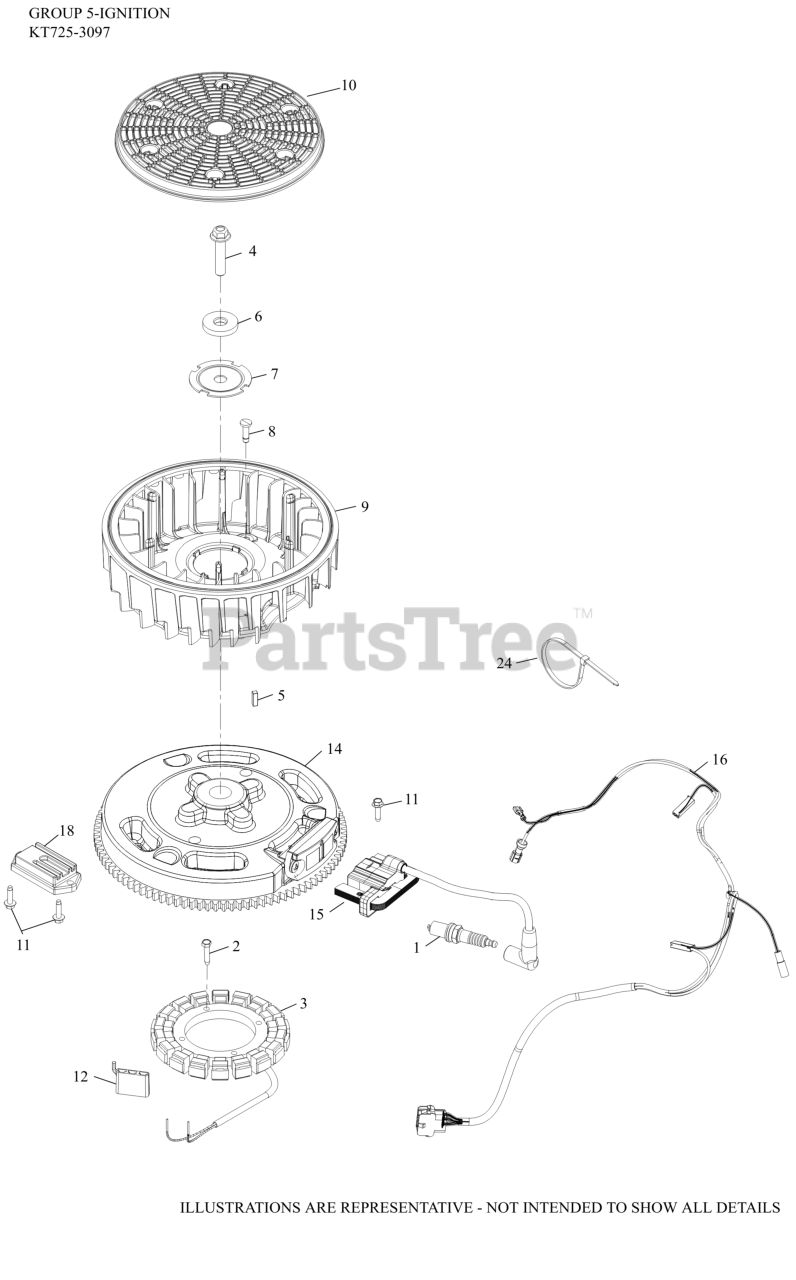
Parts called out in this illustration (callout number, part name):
1	SPARK PLUG, RFI
2	SCREW, THREAD FORMING
3	KIT, 15 / 20 AMP STATOR
4	SCREW, HEX FLANGE
5	KEY, SQUARE
6	WASHER, FLAT
7	PLATE, FAN MOUNTING
8	RETAINER, FLYWHEEL FAN
10	SCREEN, GRASS
11	SCREW, THD FRM-USE 25 086 473-S
12	CONNECTOR
14	FLYWHEEL ASSEMBLY
15	MODULE, CDI IGNITION
16	HARNESS ASSEMBLY, (MECH AUTO-CHOKE)
18	REGULATOR/RECTIFIER 12/15A HALF-WAVE STD
